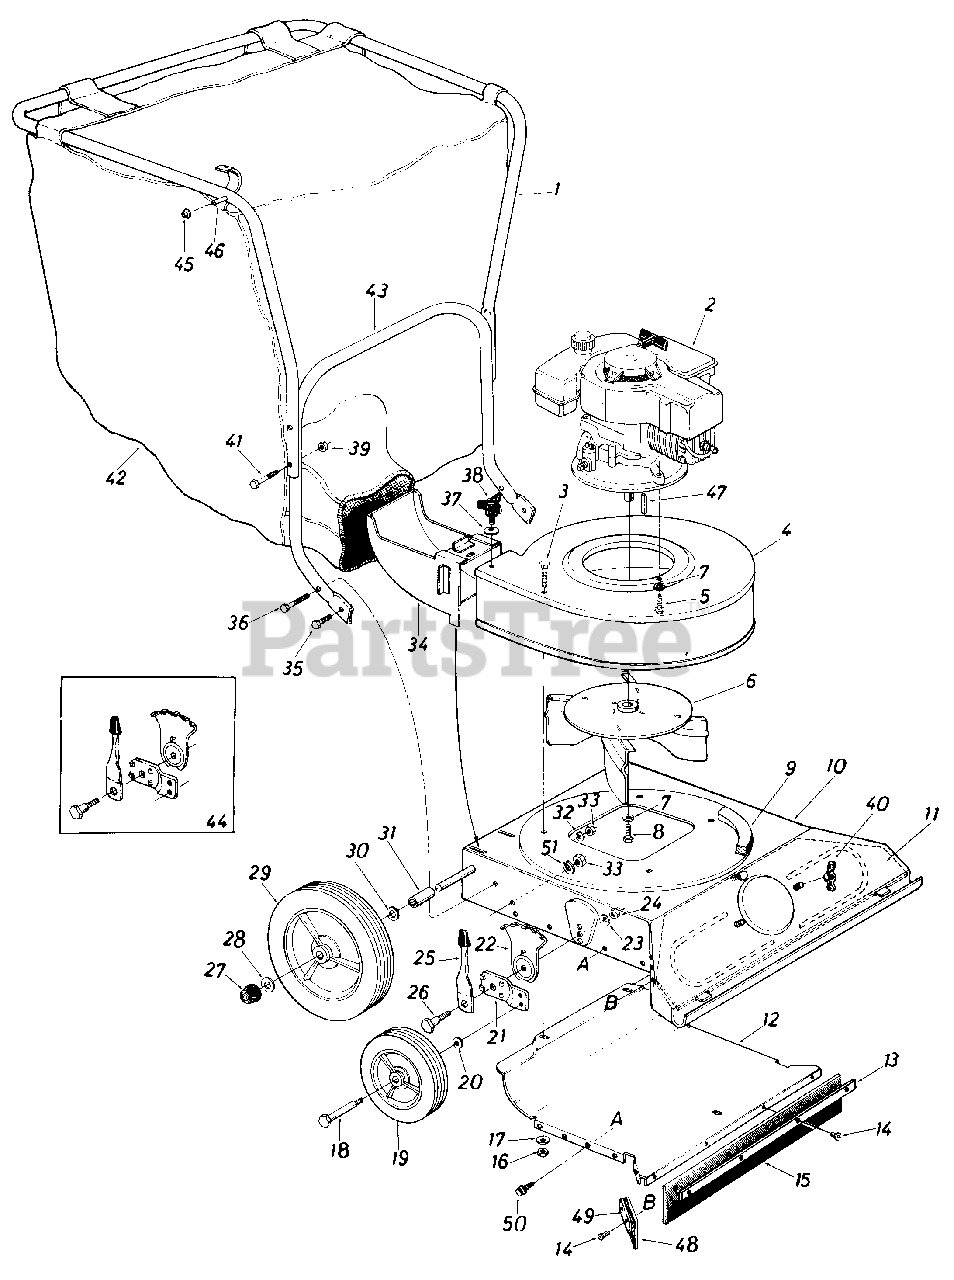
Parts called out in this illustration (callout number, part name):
1	Upper Handle (Painted)
2	Engine
3	Carriage Bolt 5/16-18 x .62" Lg.
4	Blower Housing Ass'y.
5	Hex Tap Scr. 3/8-16 x 1.00" Lg.
6	Impeller Ass y.
7	L.-Wash. 3/8" I.D.
8	Hex Bolt 3/8-24 x 1.0" Lg. w/Patch
9	P.V.C. Foam Strip (4-Pcs. 12" Lg.)
10	Vacuurn Deck Ass'y.
11	Front Baffle Ass'y.
12	Lower Baffle Ass'y.
13	Wiper Retaining Strip
14	Pop Rivet.188" Dia.
15	Nozzle Wiper Rear
16	Hex Nut 5/16-18 Thd.
17	Bell.-Wash. .34" I.D. x .87" O.D.
18	Shld. Bolt 1/2" Dia. x 1.45" Lg. (3/8-16)
19	Wheel Ass'y. Comp. 8 x 1.75" - Front
20	Bell.-Wash. .39" I.D. x 1.12" 0. D.
21	Wheel Pivot Bar
22	Index Plate
23	Bell.-Wash. .39" I.D. x 1.12" 0. D.
24	Hex Nut 3/8-16 Thd.
25	Spring Lever Ass'y. w/Knob
26	Shoulder Bolt .500" x 7/16" N Lg. (3/8-16)
27	Push Cap .50" Rod (Black)
28	Fl.-Wash. 1/2" I.D. x 1.0" O.D. x .06
29	Wheel Ass'y. Comp. 1 0 x 1 .75" - Rear
30	Fl. Wash. 1/2" I.D. x 1.0" O.D. x .06
31	Wheel Spacer 1/2" I.D. x 15/16" Lg.
32	Bell.-Wash. .39" I.D. x 1.12" O . D
33	Hex Nut 3/8-16 Thd.
34	Air Duct Ass'y.
35	Hex Bolt 3/8-16 x .75" Lg.
36	Hex Bolt 3/8-16 x 1.50" Lg.
37	Bel l.-Wash. .34" 1. D. x .87 " 0. D
38	Thumb Scr. 5/16-18 x .75" Lg.
39	Hex Cent. L.-Nut 1/4-20 Thd.
40	Wing Nut 1/4-20 (Plastic)
41	Hex Bolt 1/4-20 x 1.75" Lg.
42	Vacuum Bag (6.6 Bushel)
43	Lower Handle (Painted)
44	Height Adjuster Ass'y. Comp. R.H.
45	Push Speed Nut .25 " Dia.
46	Stud Pin .250" Dia. x 1.75" Lg.
47	Sq. Key 3/16 x 3/16 x l.OO"Lg.
48	Nozzle Wiper Side
49	Wiper Retaining Strip
50	Hex Wash. Hd. "F" Tap Scr. #l O
51	L-Wash. 3/8" I.D.
